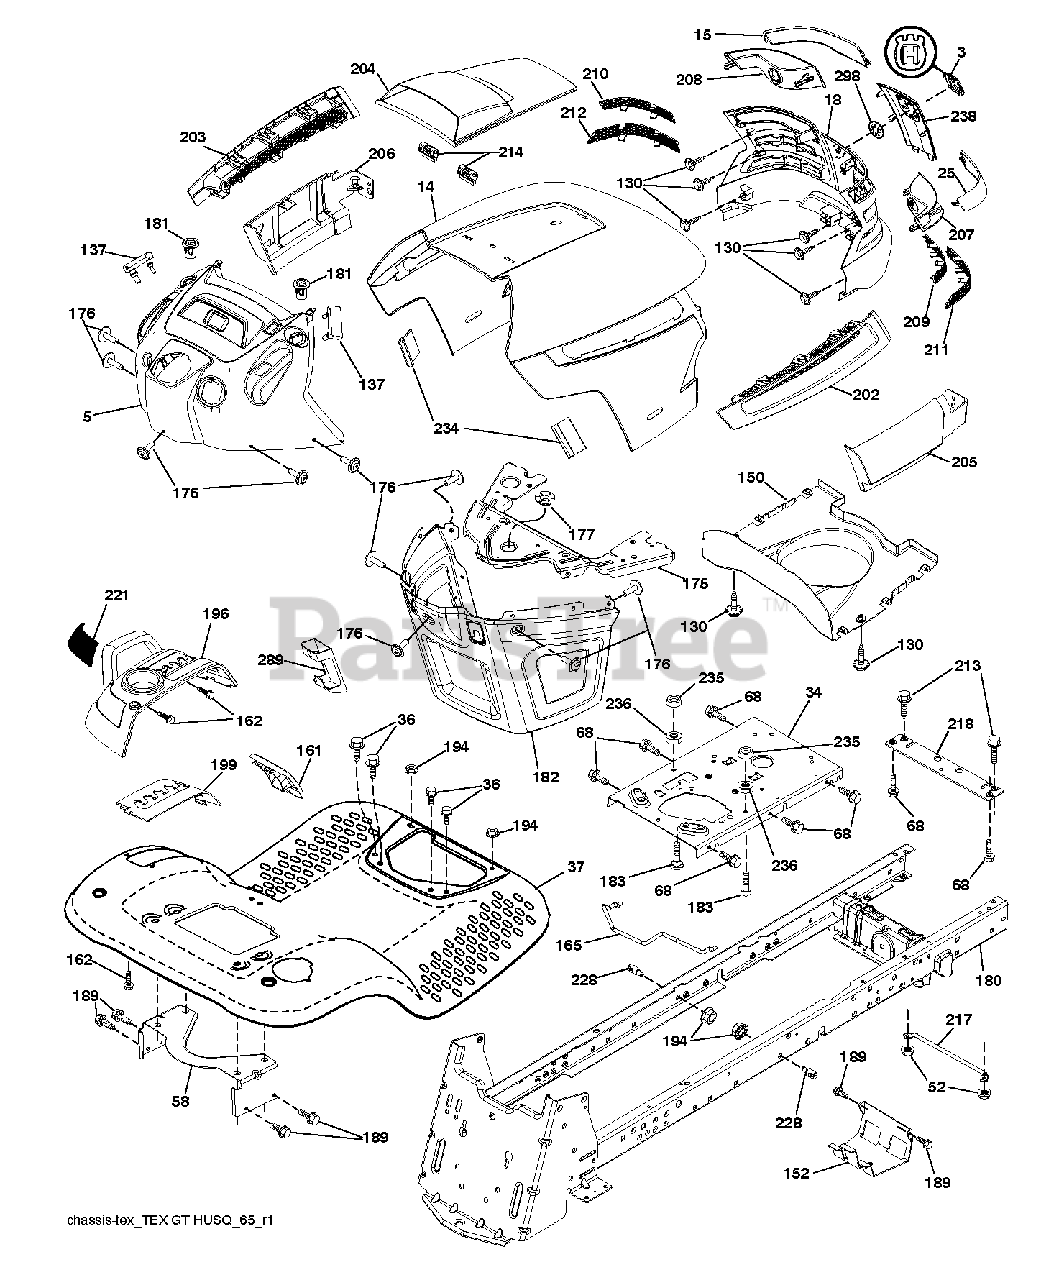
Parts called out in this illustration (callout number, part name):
3	RP LOGO
14	HOOD
15	LENS.LH.TEX.GT.HUSQ.CL
18	GRILL.ASM.HUSQ.TG/CRD.W/TRIM
25	LENS.RH.TEX.GT.HUSQ.CL
34	PLATE.ENGINE.WELDED.CHASSIS
36	SCREW 5/16"
37	FENDER.PNT.TX.GT.CH/FW.ORANGE
52	LOCKNUT
58	BRKT.SUPPORT.FNDR/TANK
68	SCREW LT
130	SCREW.#10 X 0.750.BOS
137	BUMPER DASH
150	AIR.DUCT.HOOD.TEX.GT.HUSQ
152	SHIELD.BROWNING.W/TEX
161	CONSOLE.FUEL.WINDOW.HU
162	SCREW.HI-LO.CONSOLE
165	SUPPORT.TANK.REAR.W/TEX
175	PLATE.CROSSMEMBER.HUSQ
176	SCREW.#10-24X5/8.RN.QU
177	BUSHING, STEERING
180	CHASSIS.GT.SLOPED.DRAWBAR.
181	BUSHING.MNT.FEND.CRGO.
182	DASH.LOWER.COMMON.12V.ADAPTOR
183	BOLT.5/16-18X1-1/4 FULL.THREAD
189	SCREW
194	NUT LOCK HEX FLANGE 5/16-18
196	Deck Lift Subassembly Console, Husq.Gt
199	PLATE.DECK.LIFT.HUSQVARNA.GT
202	VENT.SIDE.HOOD.RH.HUSQ
203	VENT,SIDE.HOOD.LH.HUSQ
204	HOOD VENT
205	HOOD SIDE SKIRT RH
206	SKIRT.HOOD.SIDE.HUSQ.L
207	BEZEL.RH.TEX.GT.HUSQ
208	BEZEL.LH.TEX.GT.HUSQ
209	INSERT.HEX.GRILL.HUSQ.GREY
210	INSERT.HEX.GRILL.HUSQ.
211	INSERT.HEX.GRILL.HUSQ.
212	INSERT.HEX.GRILL.HUSQ.
213	BOLT
214	CLIP.RETAINER.TINNER.
217	ROD.PIVOT.HOOD
218	X-PIECE.HOOD.STOP.NON/
221	REFLECTOR.LH.TEX GT HU
228	STUD.FASTNER.W/ANTI-ROTATE
234	BUMPER.HOOD.TEX.HUSQVARNA
235	SPACER FENDER
236	NUT.CENTERLOCK.5/16-
238	TRIM.HUSQ.TG/CRD.SERVICE
289	PLUG.N/CRUISE.COMMON.YT/GT.BLK
298	NUT PUSH M
